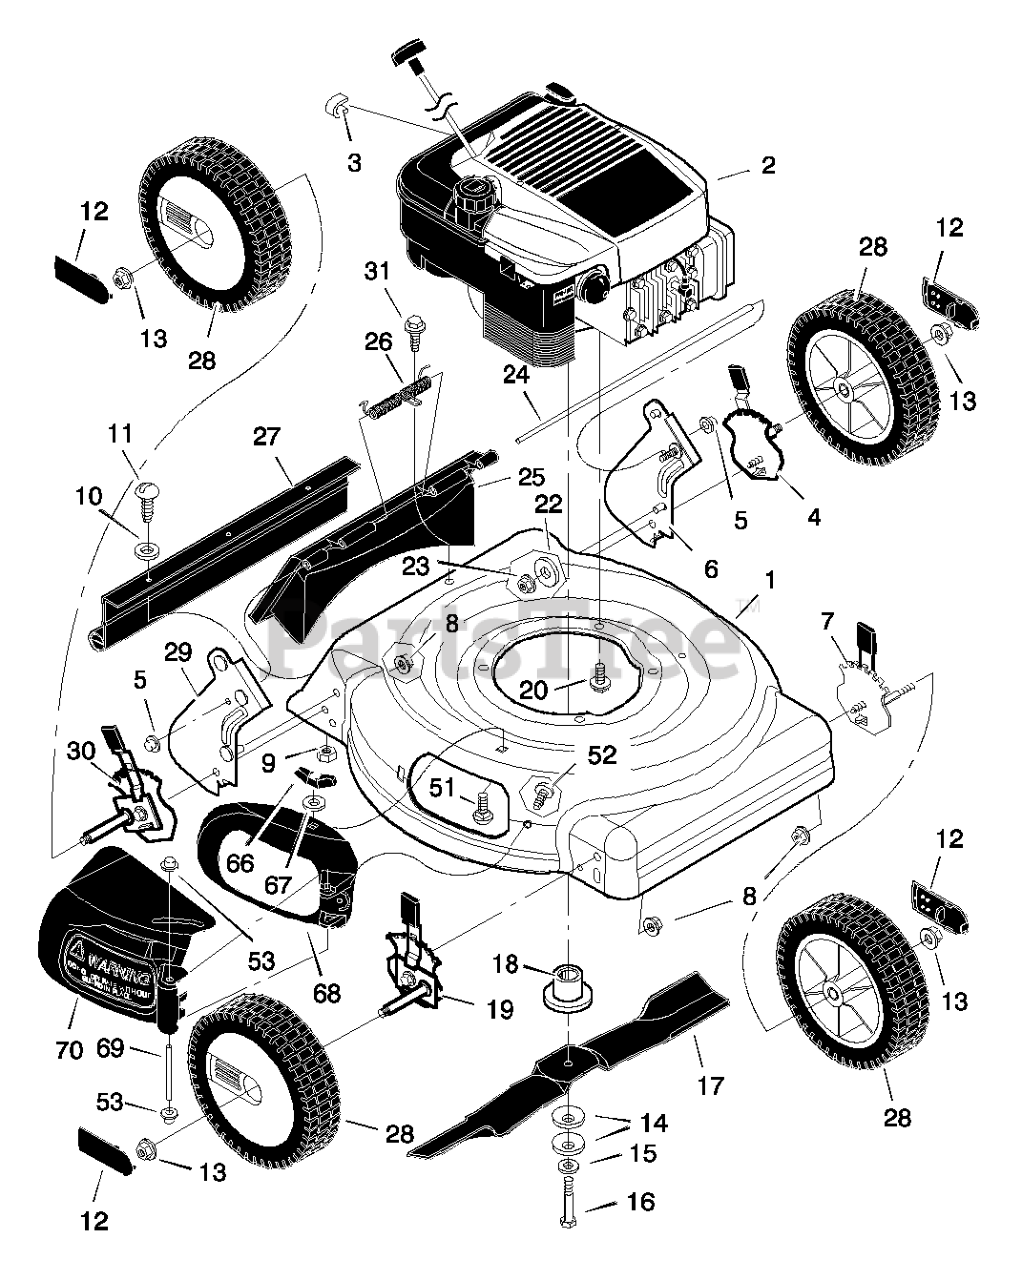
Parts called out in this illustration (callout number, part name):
1	Housing
2	Engine *
3	Stop, Rope (Recoil - Start)
4	Adjuster, Left Rear Height
5	Nut, Push
6	Bracket, Left Handle
7	Adjuster, Left Front Height
8	Nut, Flange
9	Nut, Hex
12	Hub Cap
13	Nut, Flange
14	Washer, Belleville
18	Adapter, Blade
19	Adjuster, Right Front Height
20	Bolt, Engine
22	Washer
23	Nut, Flange
24	Rod, Pivot
25	Door, Rear
27	Guard, Rear
28	Wheel (Dark Gray)
29	Bracket, Right Handle
30	Adjuster, Right Rear Height
51	Bolt, Carriage
53	Push On Cap
66	Wingnut
67	Retainer, Push
69	Pin, Pivot
70	Deflector, Chute
